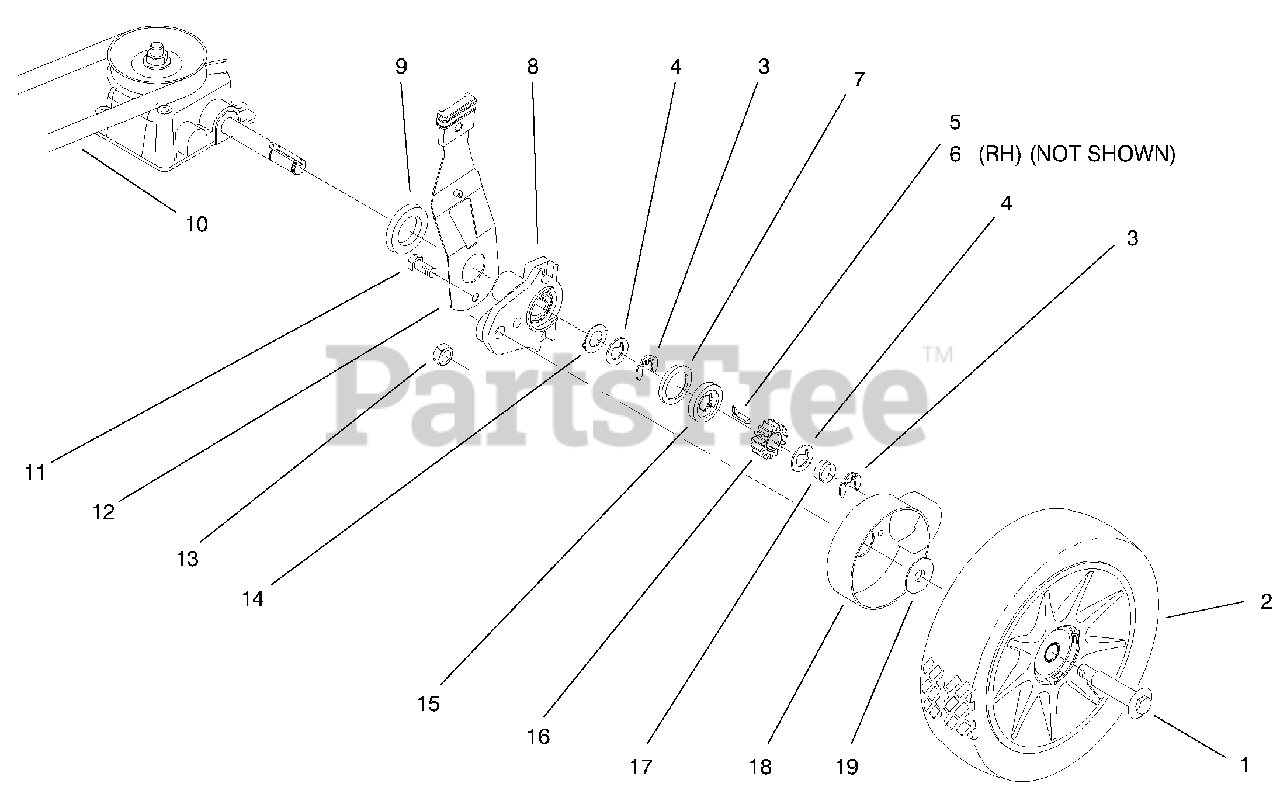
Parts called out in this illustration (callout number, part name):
1	Bolt-Shoulder
3	Ring-Retaining
4	Washer-Thrust
5	Key-Rocking
6	Key-Rocking
7	Ring-Friction
8	ASM-Hgt Adj Arm
9	Spacer-Axle Shaft
12	ASM-Spring Arm
13	Nut-Lock
14	Washer-Thrust
16	Gear-Pinion
17	Spring-Compression
18	Cover-Wheel
19	Washer-Stepped
